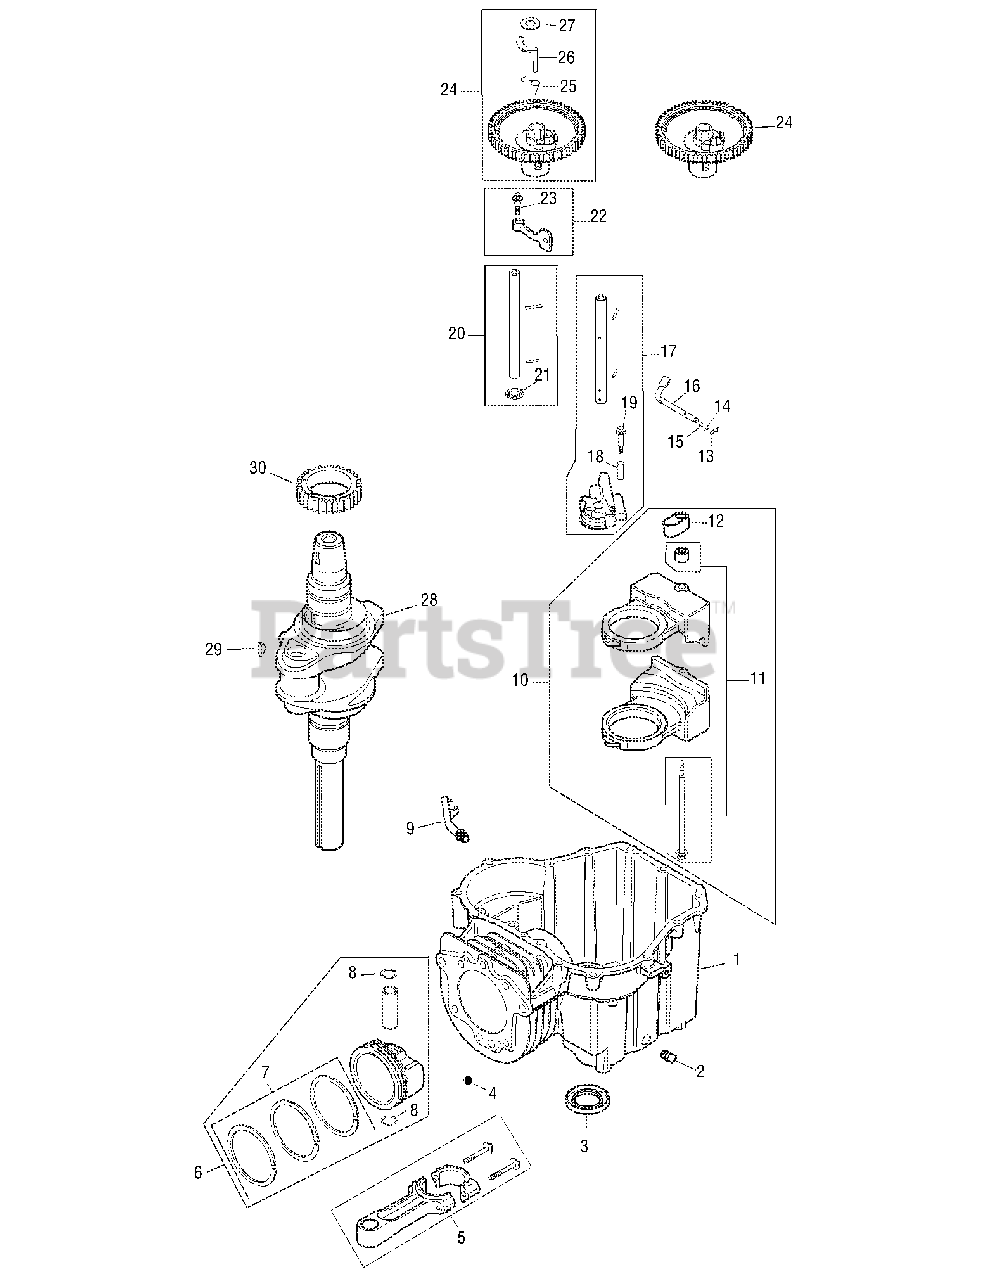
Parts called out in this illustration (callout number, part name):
1	Short Block
2	Plug, sq. hd. pipe 3/8"
3	Seal, oil
4	Check Valve Ball
5	Rod, connecting
6	Piston w/ Ring Set (Includes 7,8)
7	Ring Set (89 mm)
8	Retainer, piston pin
9	Tube, drainback
10	Kit, balance weight
11	Kit, screw/guide pin
13	Clip, hitch pin
14	Washer, plain
15	Washer, plain
16	Shaft, governor cross
17	Pump assembly, oil (Includes 17-19)
18	Spacer, oil pump screw
19	Screw, oil pump
20	Shaft center, cam
21	Washer, thrust
22	Lever assembly, cam (2) (Includes 23)
23	Screw, shoulder
24	Gear assembly, cam
26	Weight, ACR
27	Washer, thrust - ACR
28	Crankshaft (Includes ref 2)
30	Gear, crankshaft
